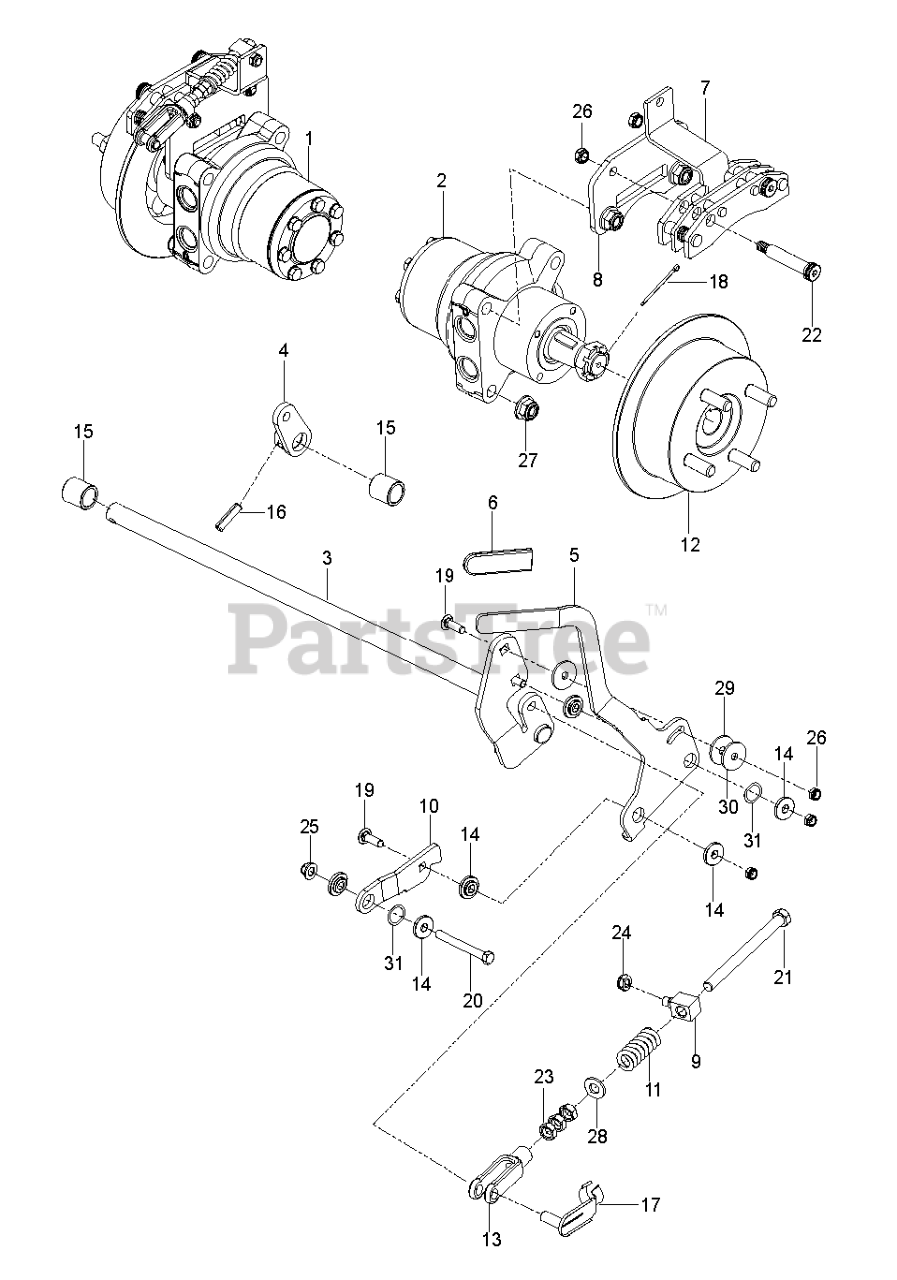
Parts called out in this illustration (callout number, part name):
1	TL15 WHEEL MOTOR
2	MOTOR, TL0240, RT
3	SHAFT, BRAKE WLDMT
4	ARM, RT BRAKE
5	LEVER.BRAKE.BLACK
8	PLATE, CALIPER
9	SWIVEL, BRAKE
10	LINK, FOLLOWER
12	HUB, DISC BRAKE, W/STUDS
13	YOKE-3/8-24 PLTD
14	BUSHING, BRAKE
15	BUSHING, SLEEVE 3/4 X 1.0
16	5/16 DIA ROLL PIN
17	PIN, CLEVIS SPRING, 3/8
18	COTTER PIN 1/8 X 2
19	BOLT.3/8-14X1.25
20	HCS 3/8-16 X 3-1/4 GR5 ZD
21	HCS 3/8F X SPECIAL
22	BOLT, SHOULDER, 1/2 X 2.25
23	NUT 3/8-24 JAM
24	5/16-18 THIN PROF NY
25	NUT 3/8-16 HEX FLG NYLOC ZD
26	NUT HEX 3/8-16 NYLON, THIN
27	NUT, 1/2-13 HEX FLG NYLOC ZD
28	WASHER
29	WASHER, FRICTION, 1/8
30	CONE WASHER
31	WASHER, .825 X 1.087, WAVE
